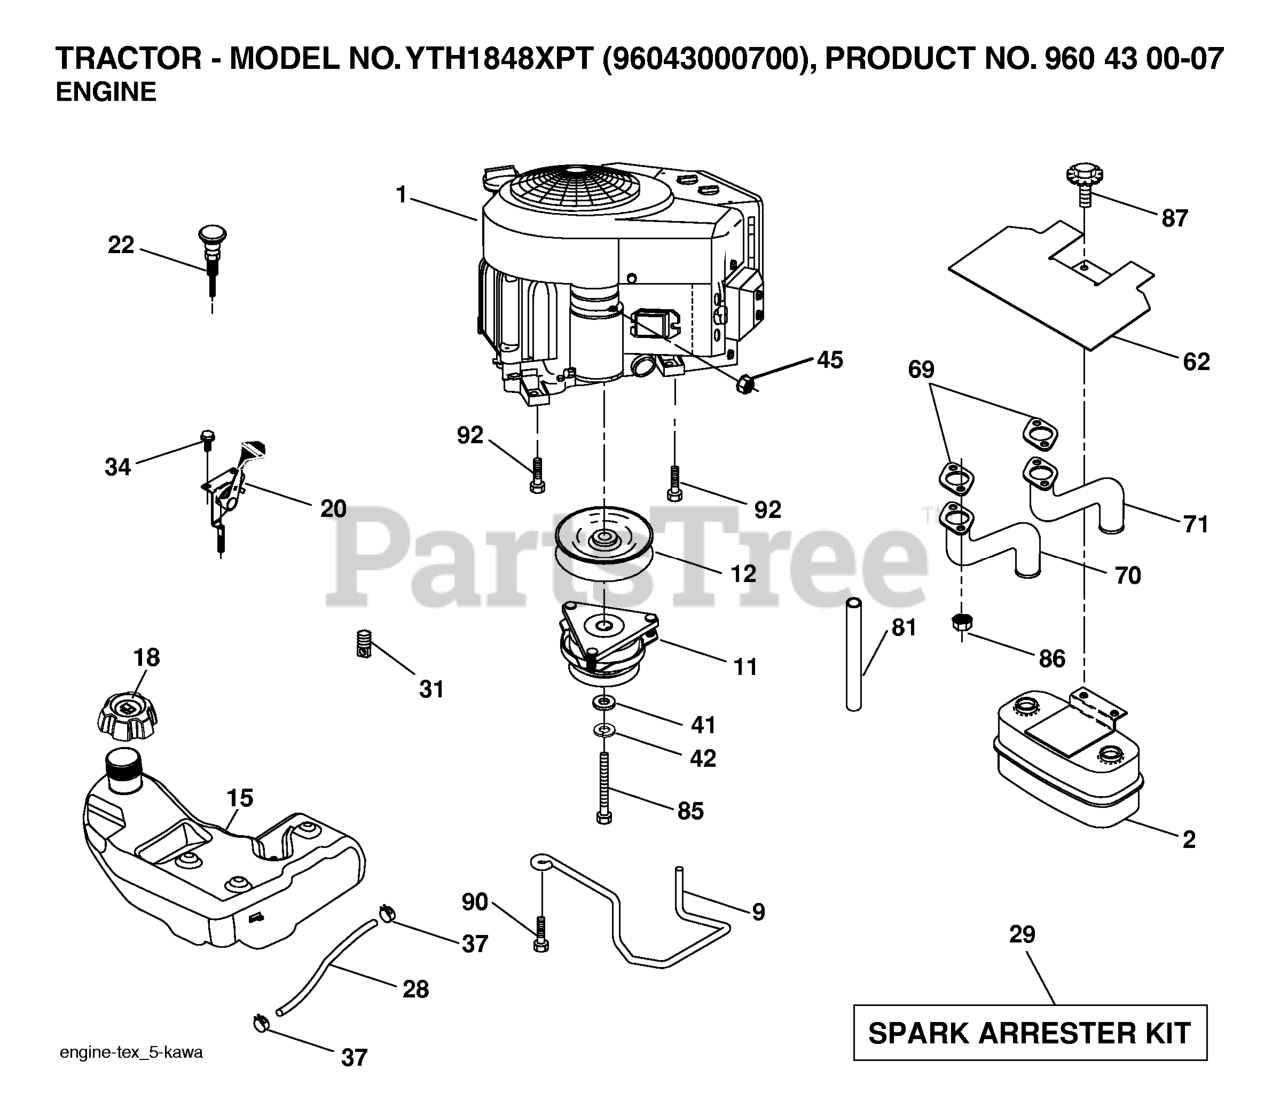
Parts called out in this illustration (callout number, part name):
2	MUFFLER.TWIN.CYL.LOW.TONE
9	KEEPER.BELT.ENGINE.4.2
11	CLUTCH ELECTRIC
12	PULLEY.ASM.ENG.OGURA.3
15	TANK.FUEL.4GAL
18	CAP.FUEL.TANK.3"GREY
20	CONTROL, THROTTLE
22	CONTROL THROTTLE
29	KIT.SPARK ARRESTOR 794945 B&S
37	HOSE CLAMP
42	LOCKWASHER
45	NUT
62	RP SHIELD HEAT MUFFLER
70	EXHAUST.TUBE.LH.KAWASAKI.
71	EXHAUST.TUBE.RH.KAWASAKI.
81	TUBE, DRAIN OIL ASM.
85	BOLT HEX 7/16-20X4-1/4"
86	NUT.HEX.FLANGE.TOPLOCK
87	BOLT.5/16-18UNCX1.W/SEMS.BLK
90	SCREW 3/8-16X1
91	BUSHING.1.375OD
92	SCREW 3/8-16X1
